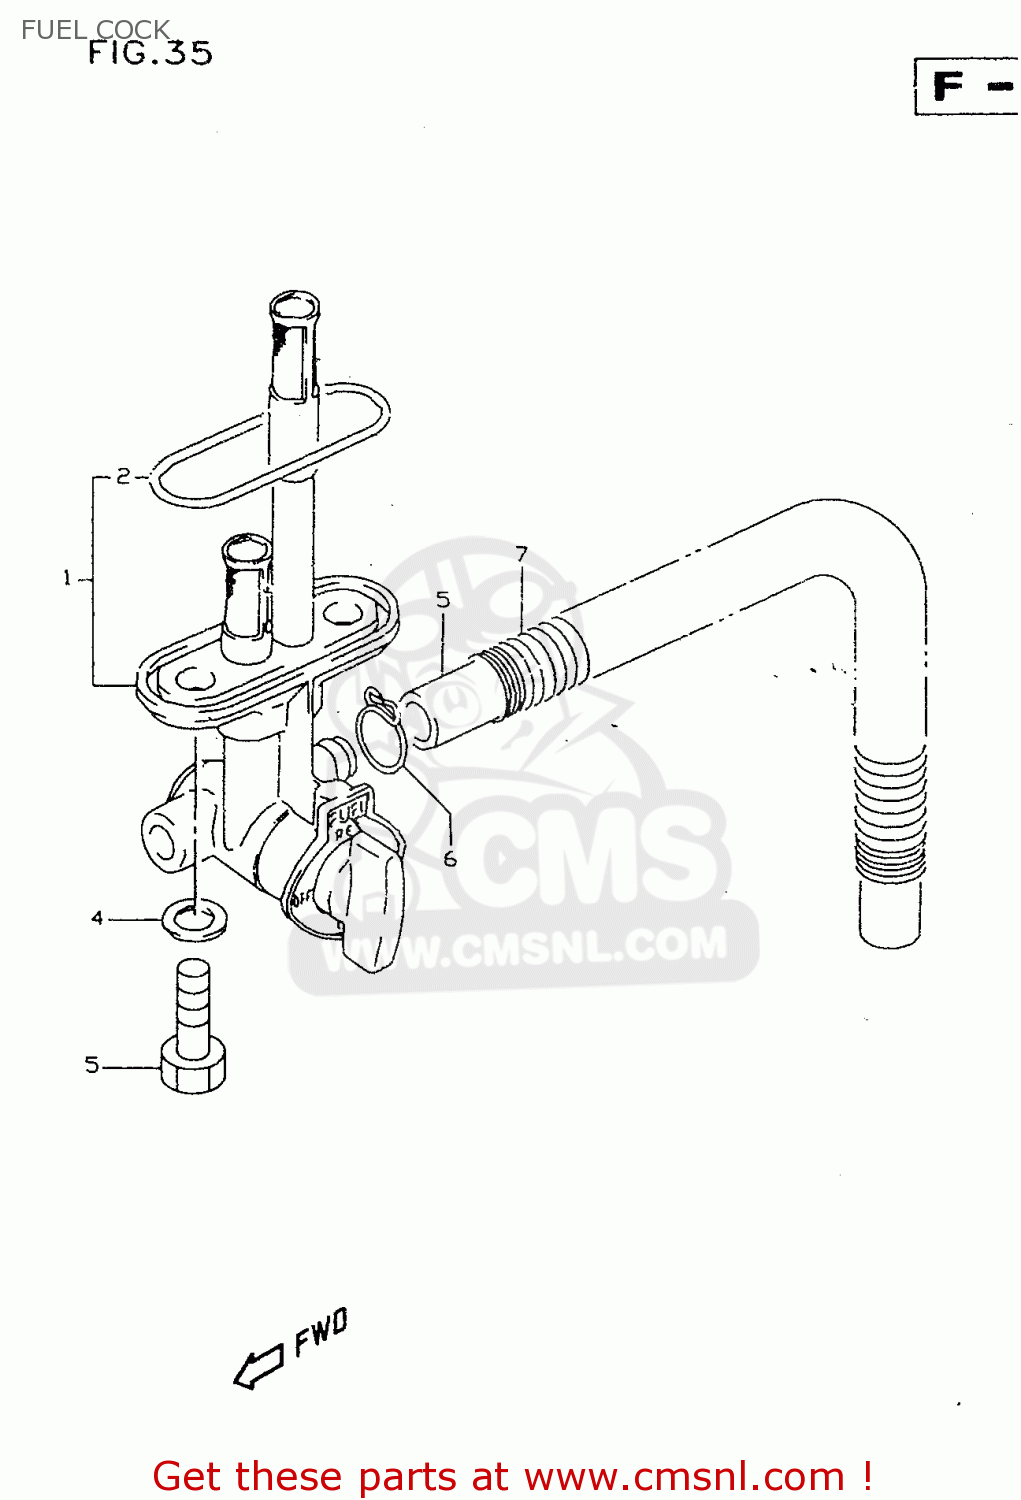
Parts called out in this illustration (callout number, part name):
1	COCK ASSY,FUEL
2	GASKET,JOINT (NAS)
3	BOLT(6X20)
4	GASKET(6.4X11.5X0.8) (NAS)
5	HOSE(7X12X600)
6	CLIP
7	SPRING
